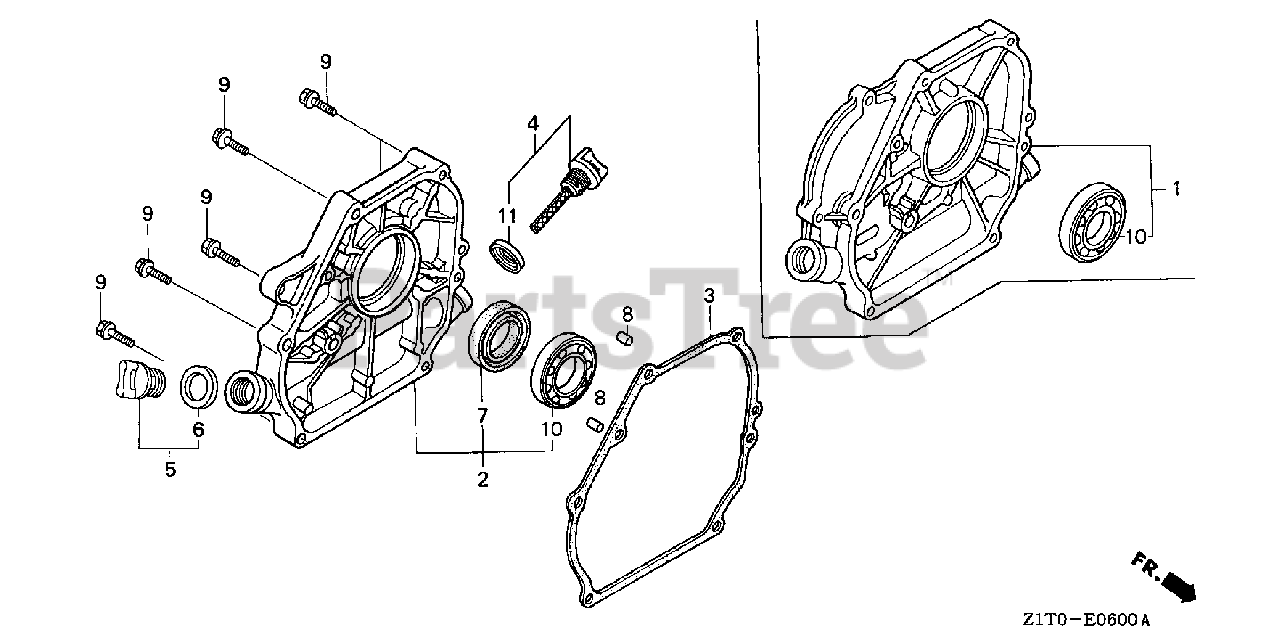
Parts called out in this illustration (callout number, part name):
2	COVER ASSY., CRANKCASE
3	GASKET, CASE COVER (NON-ASBESTOS)
4	CAP ASSY., OIL FILLER (GRAY)
5	CAP ASSY., OIL FILLER
6	GASKET, OIL FILLER CAP
7	OIL SEAL (25X41X6)
8	PIN, DOWEL (8X14)
9	BOLT, FLANGE (8X32)
10	BEARING, RADIAL BALL (6205)
11	GASKET, OIL FILLER CAP
